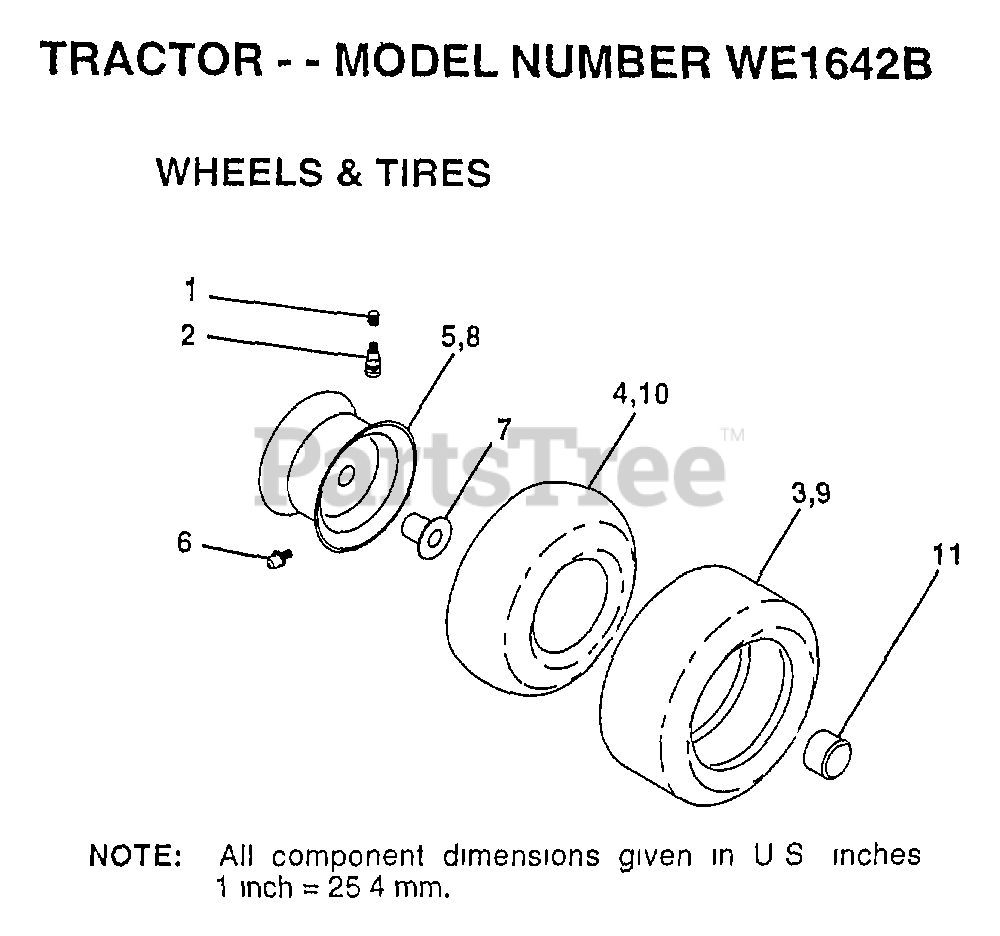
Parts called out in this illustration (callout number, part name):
1	VALVE CAP
2	VALVE STEM LT
4	TUBE.5.3/4.5/6
5	"RIM ASM 6"" FRT"
6	FITTING LT
7	"FLANGE, BEARING"
8	"RIM AS 8"" REAR"
9	TIRE.20X8-8
10	TUBE.18X9.5-8
11	HUB CAP
